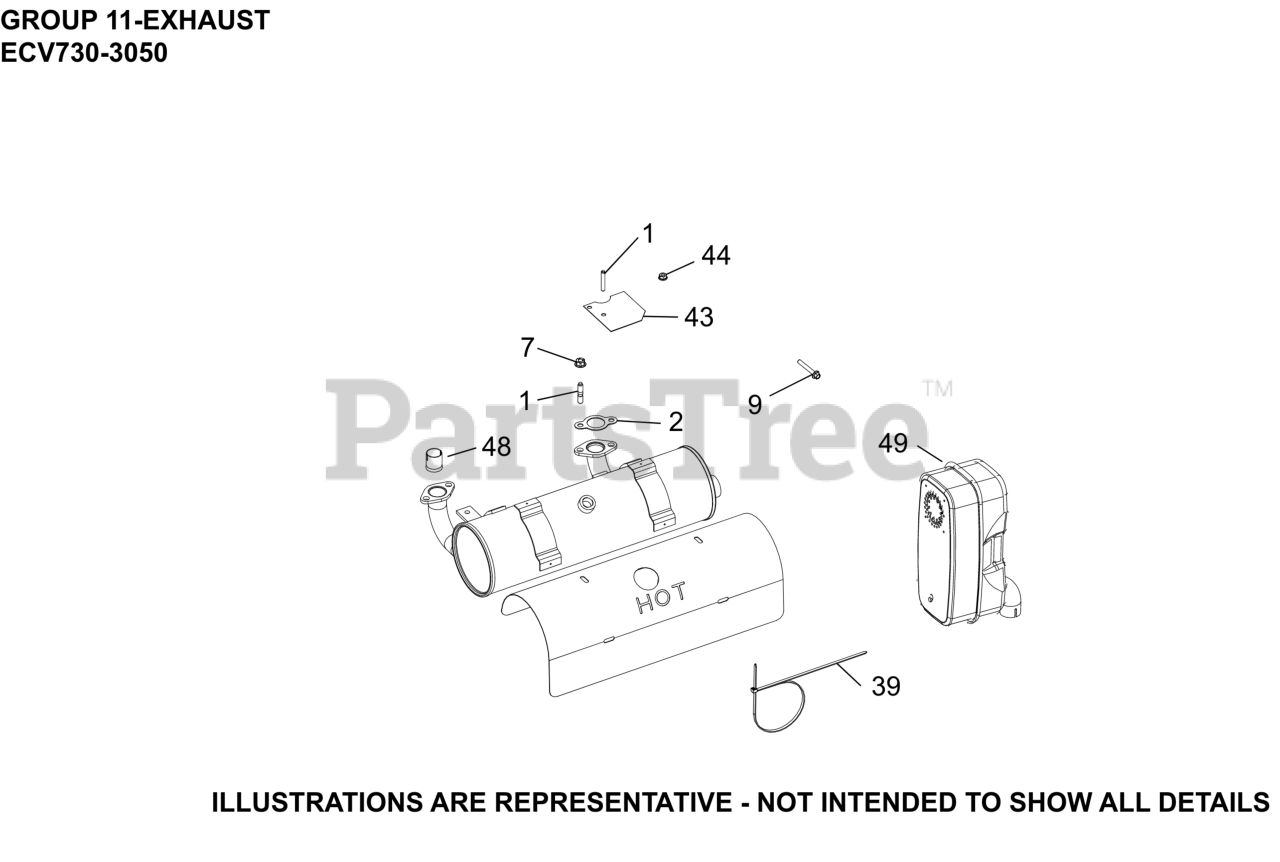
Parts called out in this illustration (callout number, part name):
1	STUD, M6X1.0X36
1	STUD, METRIC EXHAUST
2	GASKET, EXHAUST MANIFOLD
7	NUT, HEX FLANGE LOCK (M8)
9	SCREW, FLG M6X1.0X40
43	DEFLECTOR, HEAT
44	NUT, FLG M6X1.0
48	LINER, EXHAUST PORT
NI	BRACKET, MAIN SUPPORT
NI	SENSOR, OXYGEN (M12 x 1.25 THREADS)
